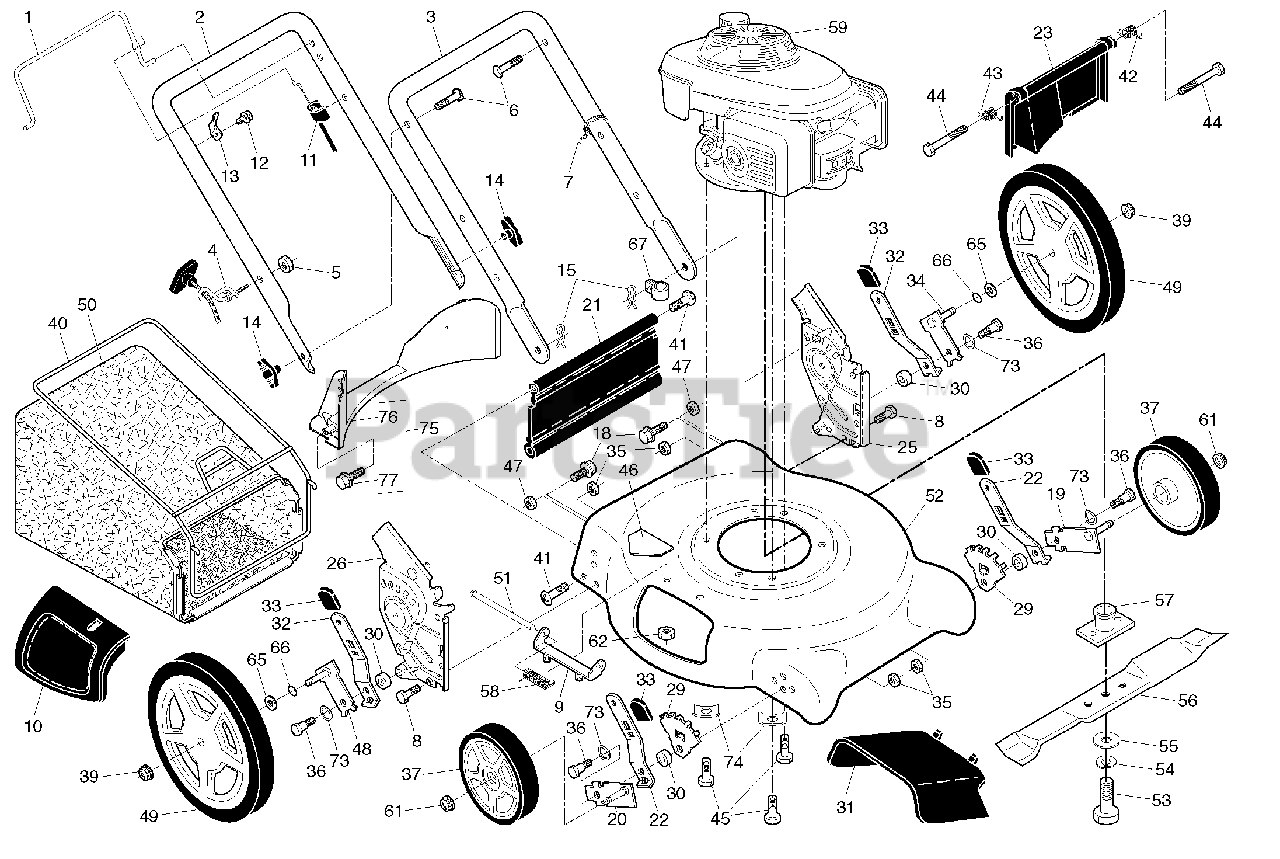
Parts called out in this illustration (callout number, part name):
1	Control Bar
2	Upper Handle
3	Lower Handle
4	Rope Guide
6	Handle Bolt
7	Wire Tie
8	Bolt, Hex Head 5/16-18 x 3/4
9	Hinge Bracket
10	Mulcher Door
11	Engine Zone Control Cable
12	Hex Washer Head Screw #10-24 x 1/2
13	Up-Stop Bracket
14	Handle Knob
15	Hairpin Cotter
18	Screw
19	Axle Arm Assembly, Front, LH
20	Axle Arm Assembly, Front, RH
21	Kit, Rear Skirt
22	Selector Spring, Front
23	Rear Door Assembly
25	Handle Bracket, LH
26	Handle Bracket, RH
29	Wheel Adjusting Bracket
30	Spacer
31	Discharge Deflector
32	Selector Spring, Rear
33	Selector Knob
34	Axle Arm Assembly, Rear, LH
35	Locknut, Hex 5/16-18
36	Shoulder Bolt 5/16-18
37	Wheel & Tire Assembly, Front, 8"
39	Nut, Hex
40	Frame, Grassbag
41	Screw, Hinge
42	Spring, LH
43	Spring, RH
44	Bolt, Rear Door
45	Hex Head Thread Rolling Screw 3/8-16 x 1
46	Danger Decal
47	Nut, Hex
48	Axle Arm Assembly, Rear, RH
49	Wheel & Tire Assembly, Rear 12 x 1-3/4
51	Hinge Rod
52	Kit, Housing
53	Screw, Hex Head, Grade 8 3/8-24 x 1-3/8
54	Helical Lockwasher
55	Hardened Washer
56	21" Blade
57	Blade Adapter
58	Hinge Spring
61	Flanged Locknut
62	Nut, Hex
65	Washer, Flat
66	O-Ring
67	Clip, Cable
73	Washer, Curved, Cylindrical
74	Washer, Special, Engine
75	Kit, Rear Baffle
76	Baffle, Rear
77	Screw, Rear Baffle
77	Operator's Manual, English
77	Operator's Manual, French
77	Repair Parts Manual
